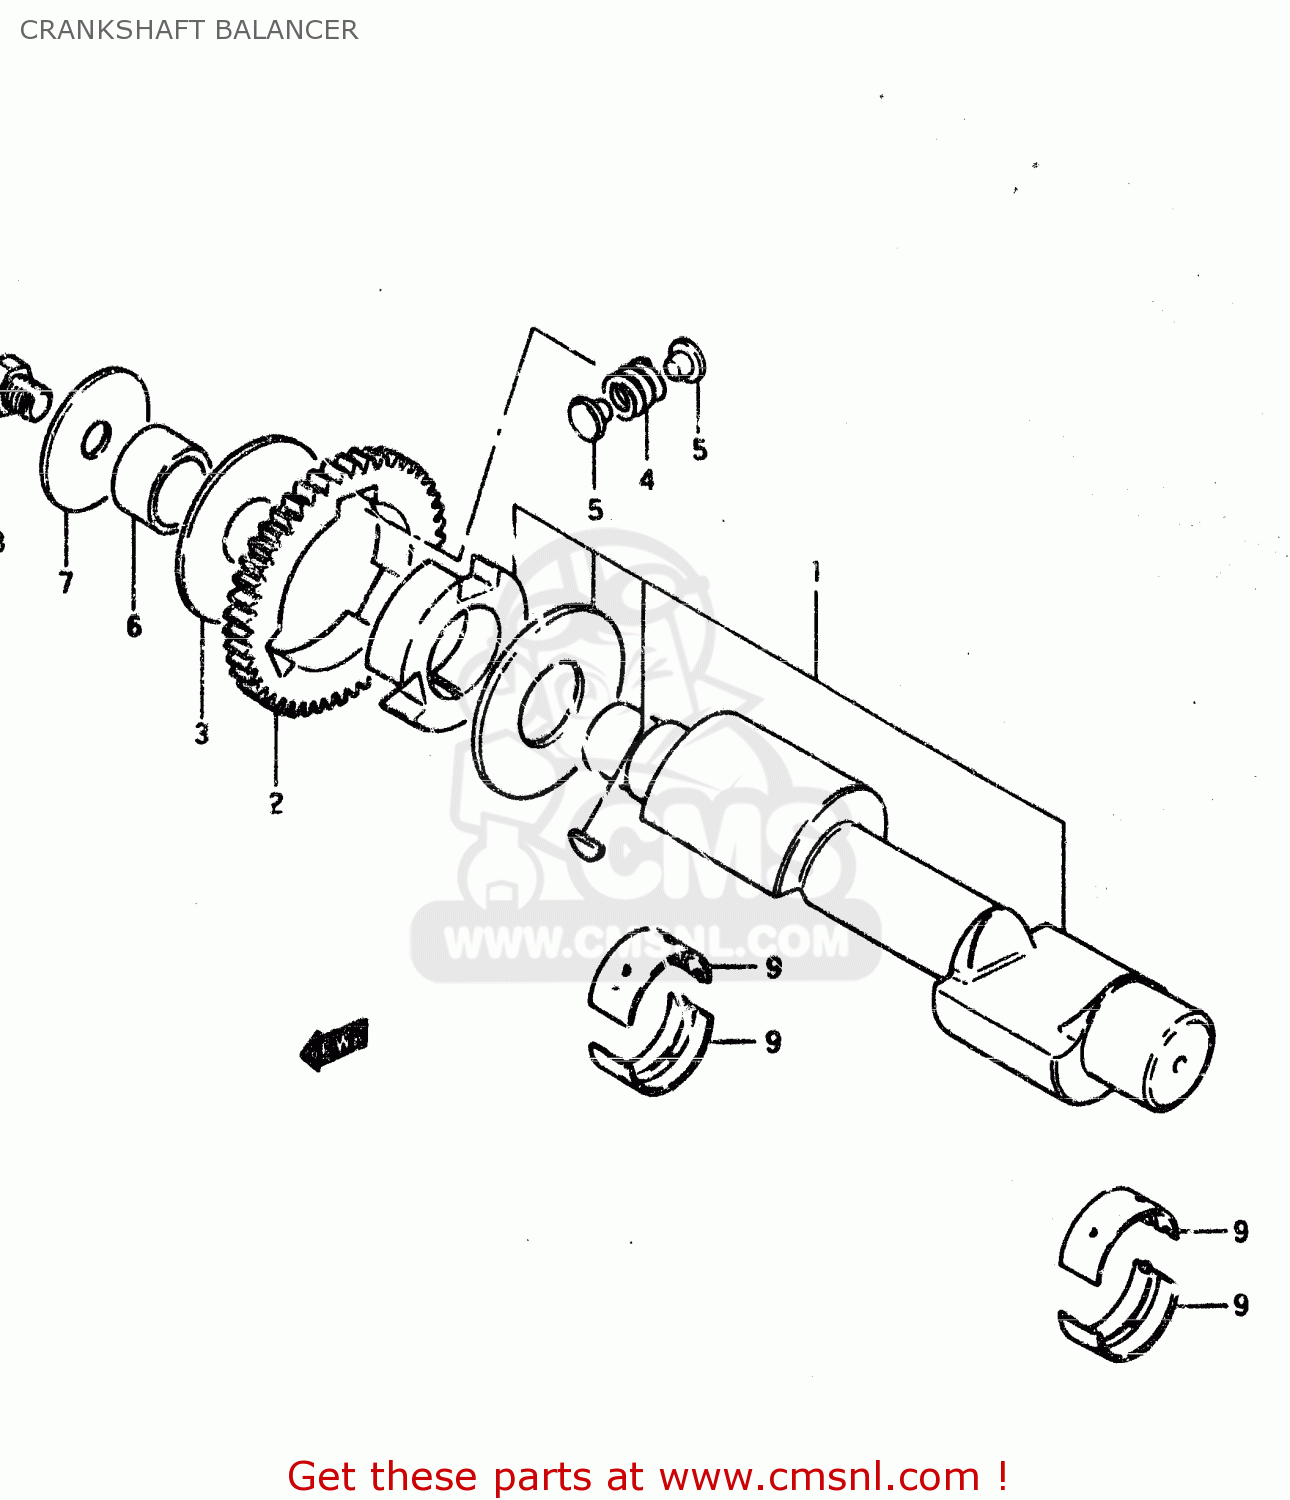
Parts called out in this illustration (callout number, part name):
1	BALANCER,CRANKSHAFT
2	GEAR,CRANK BALANCER DRIVE
3	WASHER
4	SPRING
5	PIN
6	SPACER
7	WASHER(12X50X3)
8	BOLT
9	METAL CRANKSHAFT
